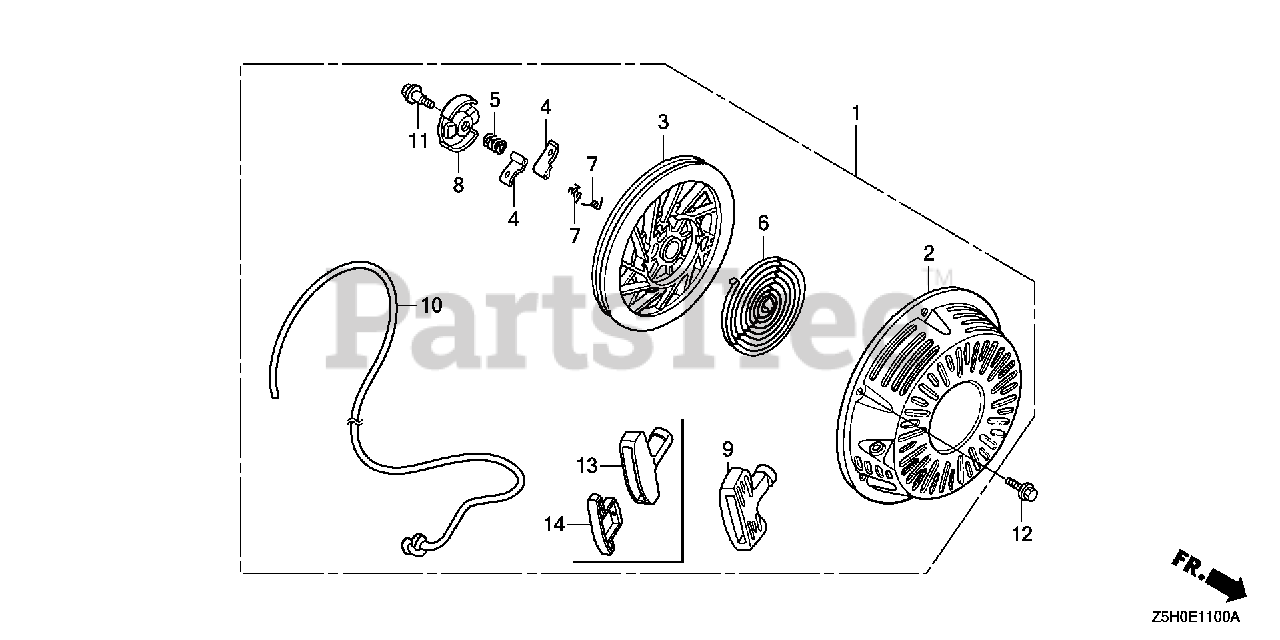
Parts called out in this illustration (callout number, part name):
1	STARTER ASSY., RECOIL *NH1* (BLACK)
1	STARTER ASSY., RECOIL *R280* (POWER RED)
2	CASE, RECOIL STARTER *NH1* (BLACK)
2	CASE, RECOIL STARTER *R280* (POWER RED)
3	PULLEY, RECOIL STARTER
4	RATCHET, STARTER
5	SPRING, FRICTION
6	SPRING, STARTER RETURN
7	SPRING, RATCHET
8	RETAINER, SPRING
9	GRIP, STARTER
10	ROPE, RECOIL STARTER
11	SCREW, CENTER
12	BOLT, FLANGE (6X10)
